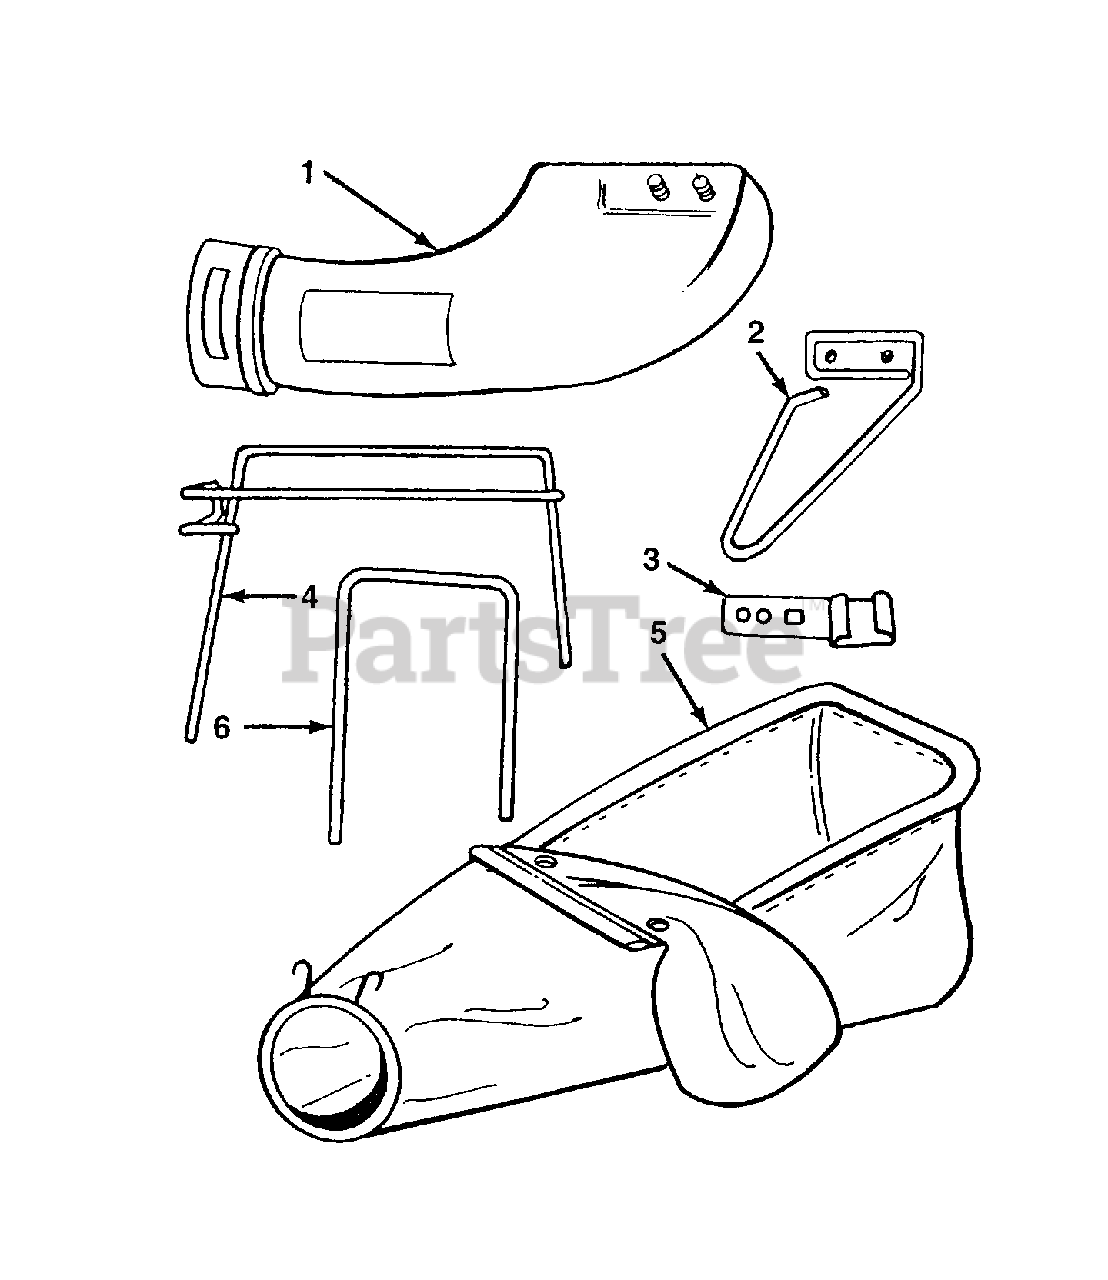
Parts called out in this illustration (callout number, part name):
1	Plastic Chute
2	Chute Mounting Bracket w/Wire
3	Handle Bracket
5	Bag w/Clamp Ring
6	Upper Support Tube
